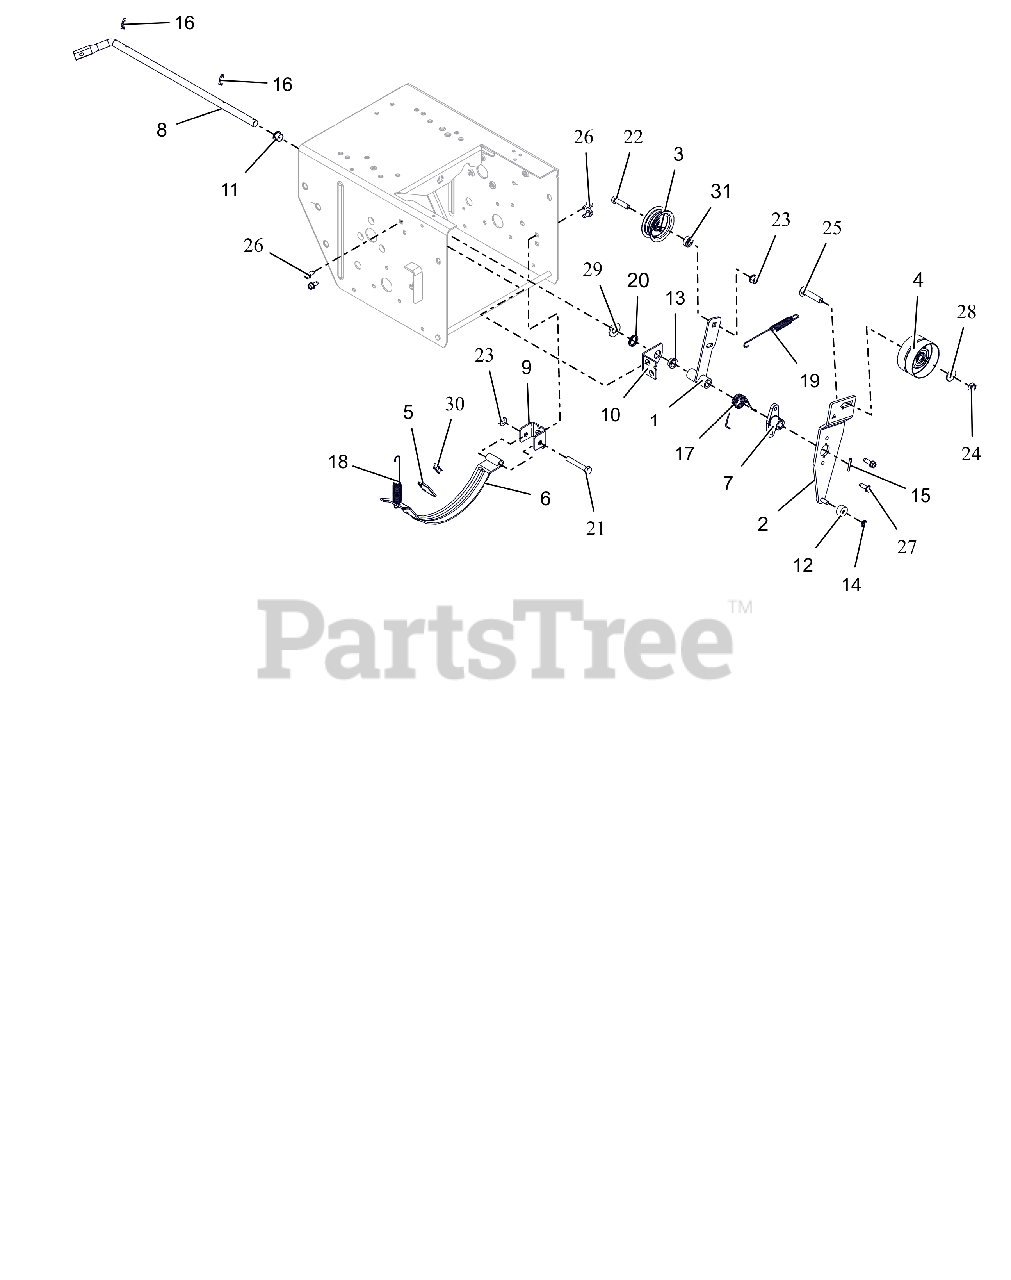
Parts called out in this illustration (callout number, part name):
1	ARM, IDLER-TRACTION
2	ARM, IDLER-ATTACHMENT
3	IDLER, FLAT - 2.00"
4	IDLER, FLAT-2.75 OD X .375 ID
5	PAD, BRAKE
6	ARM, BRAKE-ATTACHMENT
7	HUB, BRAKE ARM
8	ARM, ATTACHMENT
9	PIVOT, BRAKE
10	BRACKET, SUPPORT
11	BUSHING, POLYLINER-.50 SPLIT
12	BSHG,SLV .265 X .625 X .375
13	BSHG,FLANGE .500X.625X.270X.75
14	RG-RTNG-EXT .250X.010
15	PIN-ROLL .125X1.00
16	CLIP, SPRING
17	SG-TORS .067X.88
18	SG-TENS .056X.60X4.40
19	SG-TENS .06X.482X5.35
20	WAVE SPRING .600X.875X.25FH
21	BLT, HEX .31-18X2.00 G5 ZCC
22	BLT, HEX .31-18X1.25 G5 ZCC
23	NUT-LK-TOP-FLG .312-18 GF ZCC
24	NUT-LK-CTR-JAM .375-16 GB ZCC
25	BLT, RHSSN .38-16X1.75 G5 ZCC
26	SCR-TAP .25-20X.50 HWH ZCC
27	SCR,TAP .25-20X.75 HWH TR ZCC
28	WSHR,FLT .375X.875X.083 ZCC
29	WSHR,FLT .531X1.062X.095 ZCC
30	RVT, POP .1875 ZCC
31	SPCR, BRG .315X.500X.358X.281
